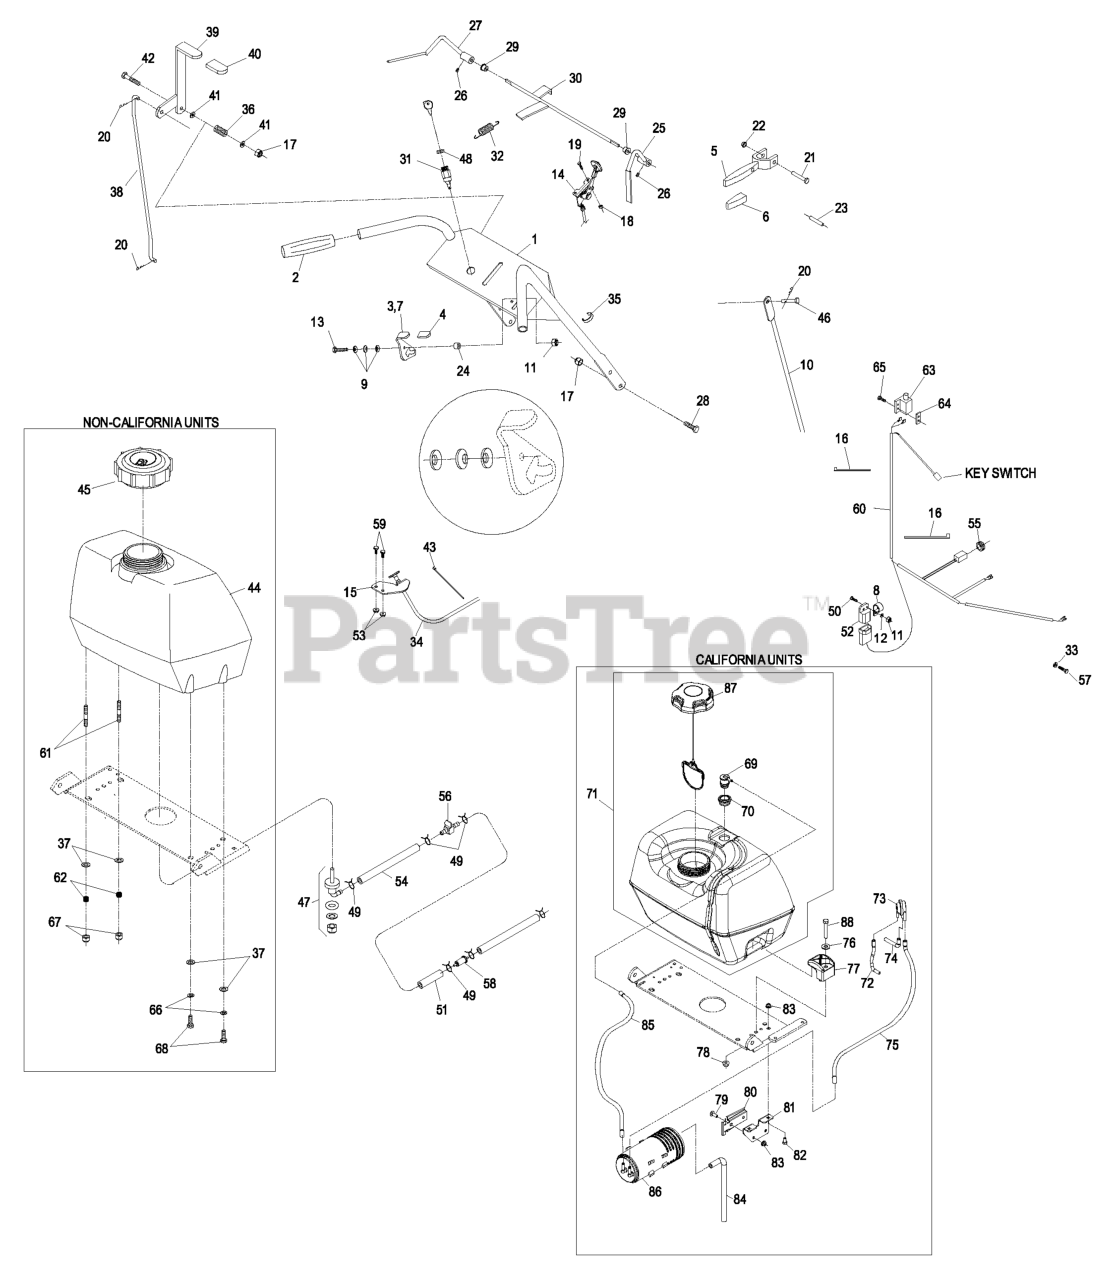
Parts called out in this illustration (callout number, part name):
1	KIT,HANDLE W/DECALS METRO
4	GRIP-LATCH
5	DRIVE LEVER ASM
6	GRIP-LEVER, DRIVE
8	CLIP-LOOM
9	WASHER-SPRING
10	LINKAGE-WHEEL, DRIVE
11	NUT-LOCK, NI
12	WASHER-FLAT
13	SCREW-HH
14	CONTROL, THROTTLE
15	BRACKET-CABLE, CHOKE
16	TIE-CABLE
17	NUT-LOCK, NI
18	NUT-LOCK, NI
19	BOLT-CARR
20	PIN-COTTER
21	PIN-LEVER, DRIVE
22	NUT-PUSH
23	PIN-ROLL
25	LEVER-RH
26	SCREW-SET
27	LEVER-LH
28	SCREW-HH
29	BUSHING-NYLON
30	WLD,ROD OPC
31	SWITCH & KEY (INCLUDES NU
32	SPRING-EXTENSION
33	WASHER-PLAIN
34	CABLE-CHOKE
35	CLIP-CABLE
36	SPRING-COMPRESSION
37	WASHER-PLAIN
38	LINKAGE-BLADE, UPPER
40	GRIP-LEVER
41	WASHER-FLAT
42	SCREW-HH
43	TIE-PLASTIC
44	ASM,FUEL TANK W/B
45	CAP-FUEL, GAS
46	PIN-CLEVIS
47	FITTING-FUEL, BULKHEAD
48	NUT-SWITCH, IGNITION
50	SCREW-HH
51	HOSE-FUEL
52	MODULE-INTERLOCK
54	HOSE-FUEL
55	GROMMET
56	VALVE-FUEL
57	SCREW-HH
58	Pn 41019-1055 W/6" Fuel Line
59	SCREW-HH
60	HARNESS-WIRE
61	STUD
62	SPRING-TANK, FUEL
63	SWITCH-OPEN, NORMALLY
64	PLATE-TAPPED
65	SCREW-PPH
66	WASHER-LOCK
67	NUT-LOCK, NI
68	SCREW-HH
72	HOSE-VENT, FORMED
73	VALVE-CONTROL, VACUUM
74	HOSE-VENT, FORMED
75	HOSE-VENT, FORMED
76	WASHER-FLAT
78	NUT-HF, NI
79	SCREW-HH
80	BRACKET-CANISTER, CARBON
81	BRACKET-CANISTER, CARBON
82	BOLT-CARR
84	HOSE-VENT, CANISTER
85	HOSE-VENT
86	CANISTER-CARBON, 800CC
88	SCREW-HH
